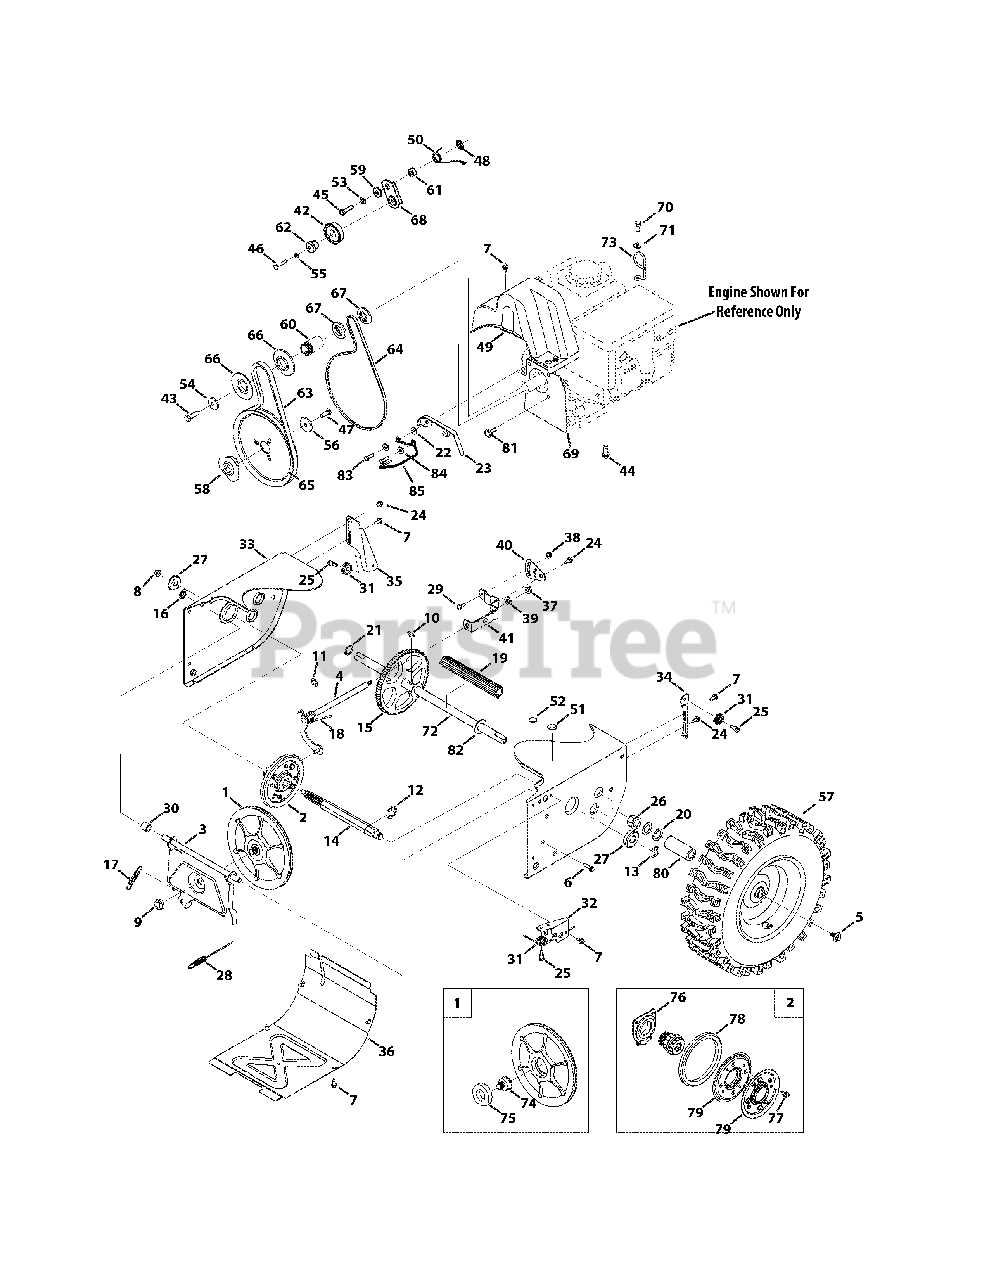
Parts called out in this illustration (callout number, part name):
1	Disc Assembly, Friction Wheel
2	Friction Wheel Assembly, 5.5 OD
3	Friction Wheel Support Bracket
4	Rod Shift Assembly
5	Screw, 5/16-24 x .750
6	Taptite Screw, 1/4-20 x 1.000
7	Taptite Screw, 1/4-20 x .625
8	Flange Lock Nut, 3/8-16
9	Flange Nut, 5/8-18
10	Hi-pro Key, 3/16 x 3/4 Dia.
12	Retaining E-Ring, .875 Dia.
13	E-Ring, .750 Dia.
14	Hex Shaft, 7-Tooth
15	Gear, 80-Tooth
16	Speed Nut, .500
17	Extension Spring
18	Torsion Spring, .750 x .968
19	Axle Spacer
20	Flat Washer, .793 x 1.24 x .060
21	Flat Washer, .75 x 1.00 x .060
22	Washer, Flat, .330 x .687 x .030
23	Belt Cover
24	Shoulder Screw, .368 x .113, 1/4-20
25	Shoulder Screw, 1/4-28, .340 x .355
26	Hex Flange Bearing
27	Ball Bearing, 17 x 40 x 12
28	Wheel Clutch Cable, 44.955"
29	Hex Head Screw, 1/4-20 x .620
30	Spacer, .508 ID x .75 OD x .68
31	Cable Roller
32	Auger Cable Front Guide Bracket
33	Frame
34	Auger Cable Guide Bracket
35	Drive Cable Guide Bracket
37	Flange Lock Nut, 5/16-18
38	Flange Lock Nut, 1/4-20
39	Washer, Flat, .469 x .875 x .105
40	Speed Selector Pivot Bracket
41	Speed Selector Shift Bracket
42	Idler Pulley Assembly
43	Hex Screw, 3/8-24 x 1.25
44	Sems Screw, 3/8-16 x 1.00
45	Hex Screw, 5/16-24 x 1.25
46	Hex Screw, 1/4-20 x 1.25
47	Hex Head Screw, 5/16-24 x .875
48	Push-on Nut, .25 Dia.
50	Torsion Spring, .850 ID x .333
51	Plug, 3/8 ID
52	Plug, 1/2 ID
53	Lock Washer, 5/16
54	Flat Washer, .45 x 1.5 x .172
55	Washer, Lock, 1/4
56	Flat Washer, .34 x 1.50 x .150
57	X-Trac Wheel, 15 x 5 x 6, LH
57	X-Trac Wheel, 15 x 5 x 6, RH
58	Adapter Pulley, .75 Dia.
59	Shoulder Spacer, .3175 x .5 x .0975
60	Spacer, .875 ID x 1.185 OD
61	Spacer, .340 x .750 x .330
62	Shoulder Space, .260 x .785 x .538
63	Auger Drive Belt
64	Wheel Drive Belt
65	Auger Drive Pulley, 8.1 x .5
66	Pulley Half, 2.600 OD
67	Pulley Half, 3/8 x 1.716 OD
68	Wheel Drive Idler Bracket
69	Cover Plate
70	Hex Head Screw, 1.25 x 20
71	Washer, Flat, .330 x .630 x .0635
72	Axle, .75 x 22
73	Cable Guide
74	Friction Disc Bearing Pin
75	Ball Bearing, 30 x 55 x 13
76	Bearing Assembly
77	Taptite Screw, 5/16-18 x .750
78	Friction Wheel Rubber
79	Friction Wheel Plate
80	Spacer, 1.25 x .75 x 3.0
81	Shoulder Screw, .500 x .145
82	Washer, Flat, .760 x 1.49 x .060
83	Hex Head Screw, 5/16-24 x 1.00
84	Washer, Flat, .349 x .879
